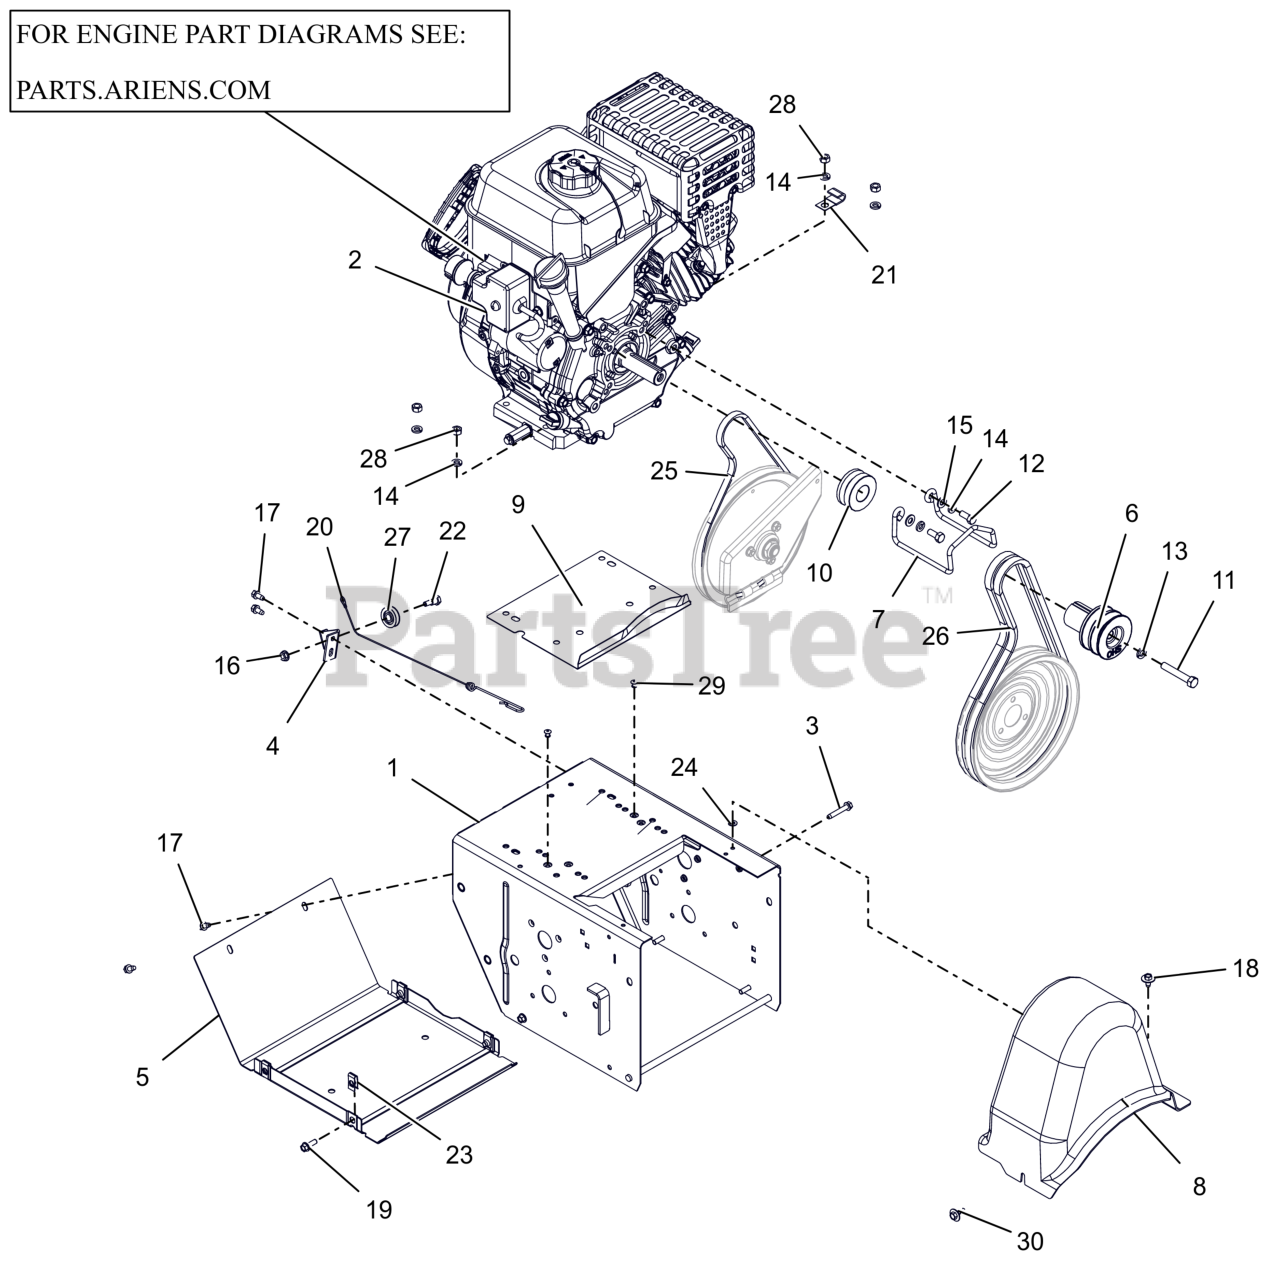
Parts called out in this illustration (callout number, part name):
1	FRAME, MAIN - 14GA DELUXE (ORANGE)
2	ENGINE, ARIENS AX291 240V/60W
3	SCR,TAP .25-20X1.50 HWH TR ZCC
4	BRACKET, CABLE PULLEY
5	COVER, BOTTOM
6	SHEAVE,ATTACHMENT-SHO 2 GRV
7	FINGER, BELT
8	COVER, BELT-LARGE
9	BAFFLE, WATER - LARGE BLOCK
10	SHEAVE, TRACTION (KEYLESS)
11	BLT, HEX .38-24X2.25 G5 ZCC
12	BLT, HEX .31-24X.750 G5 ZCC
13	WSHR,LK-REG .375X.094 ZCC
14	WSHR, LK-HVY .312X.097 ZCC
15	WSHR,FLT .344X.688X.065 ZCC
16	NUT-LK-TOP-FLG .250-20 GF ZCC
17	SCR-TAP .25-20X.50 HWH ZCC
18	SCR, TAP .25-20X.50 LG HWH ZCC
19	BLT, HWH .25-20X.75 G5 ZCC
20	CABLE, LOWER TRACTION,SS & PRO
21	J-CLAMP
22	BOLT, SHLDR -.375 X .375 X .25-20
23	NUT-RTNR .25-20X.56
24	NUT-PUSH .25X.50 O.D.
25	V-BELT, 3L-WRAPPED
26	V-BELT, HA-RAW EDGE (SET)
27	PULLEY, CABLE
28	NUT, HEX .312-18 ZCC
29	RVT, POP .1875 ZCC
30	SCR-TAP .25-20X.5 CAPTIVE
